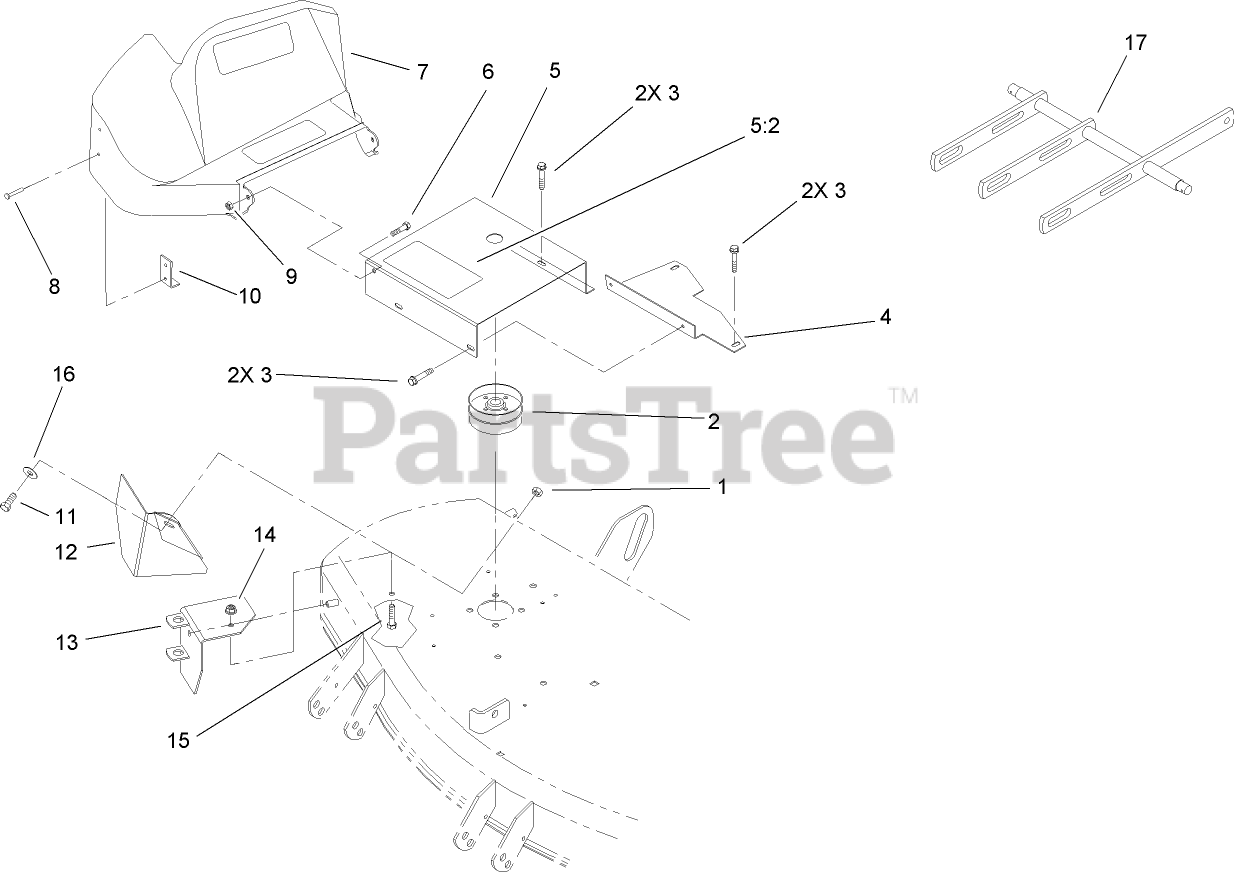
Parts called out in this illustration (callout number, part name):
1	NUT-LOCK, NI
2	PULLEY
3	SCREW-HWH
4	ADAPTER-SHIELD
5	SHIELD / DECAL ASM
5:2	DECAL-DANGER
6	SCREW-HH
7	SHIELD-BELT
8	RIVET-POP
9	NUT-LOCK, NI
10	BRACKET-SUPPORT, SHIELD
11	SCREW-HH
12	DEFLECTOR
13	PIVOT BRACKET ASM
14	NUT-HF
15	SCREW-HH
16	WASHER-FLAT
